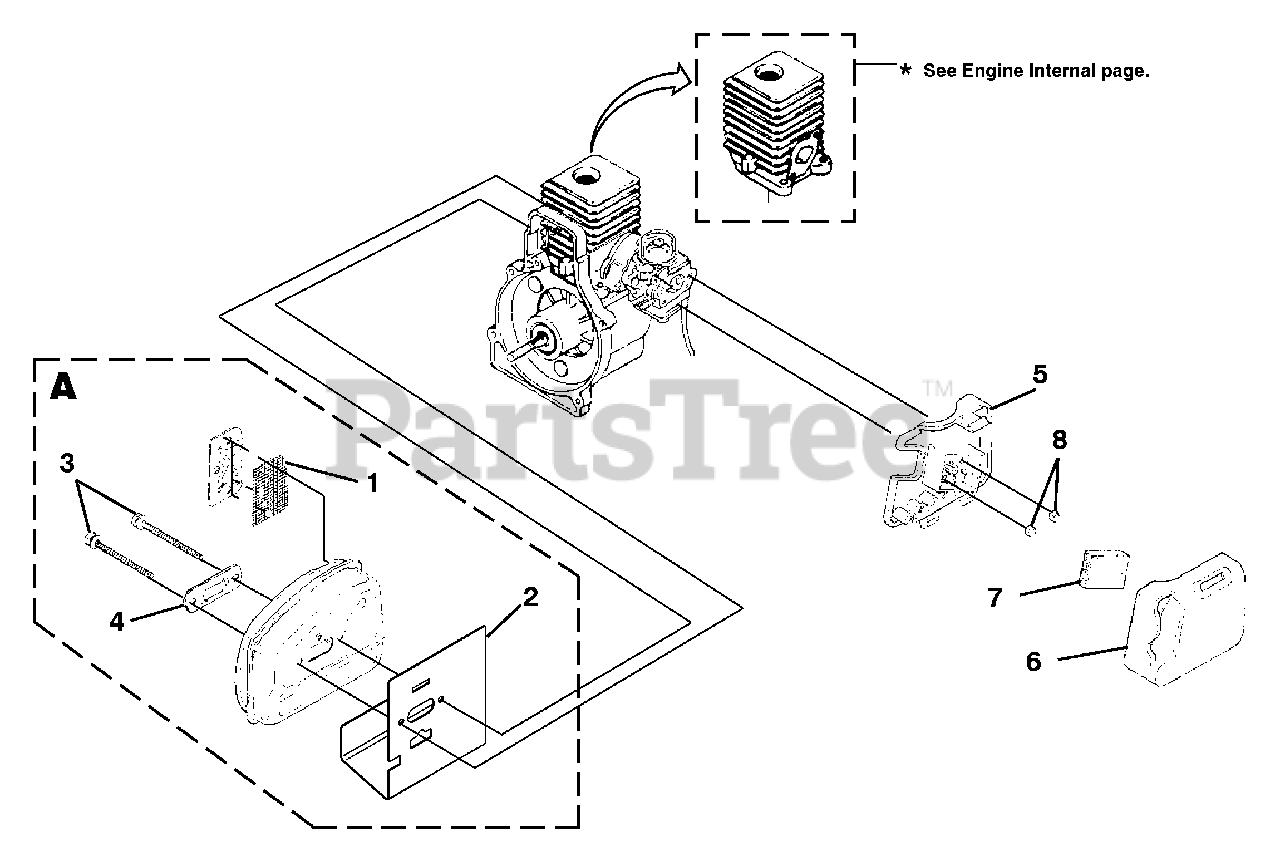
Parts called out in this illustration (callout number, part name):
1	SCREEN-Spark
2	GASKET Muffler
4	PLATE Reiforcemet
5	AIR FILTER BOX
6	COVER-Air Box
7	FILTER-AIR
8	NUT-Hex (10-24)
A	MUFFLER ASSY.
